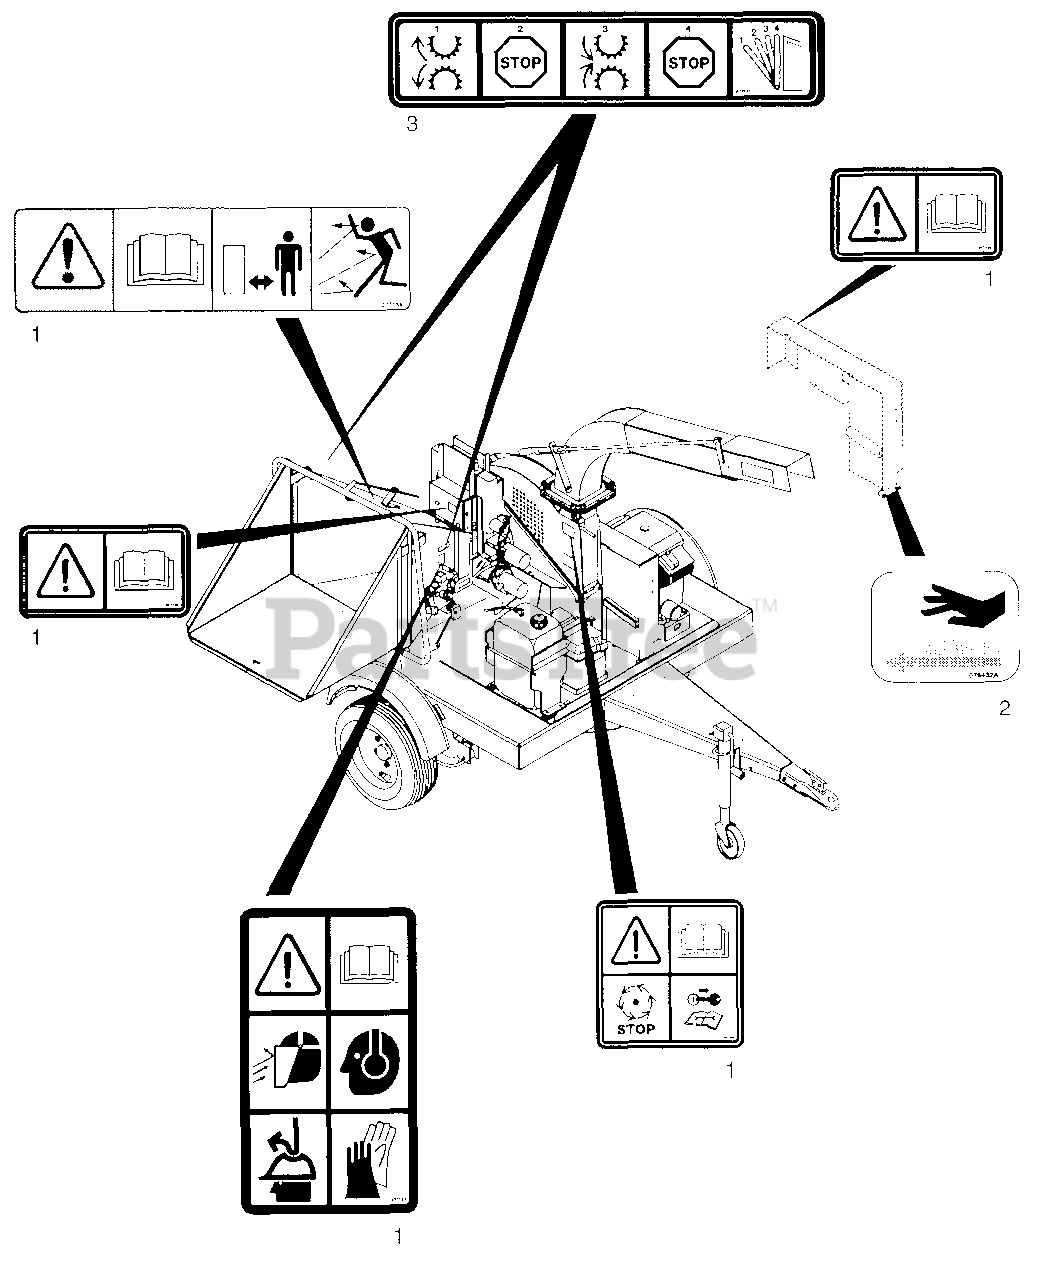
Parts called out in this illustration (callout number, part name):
1	Decal Set - Chipper CE
2	Decal - Hot Surface
3	Decal Set - Chipper BLK/WHT
